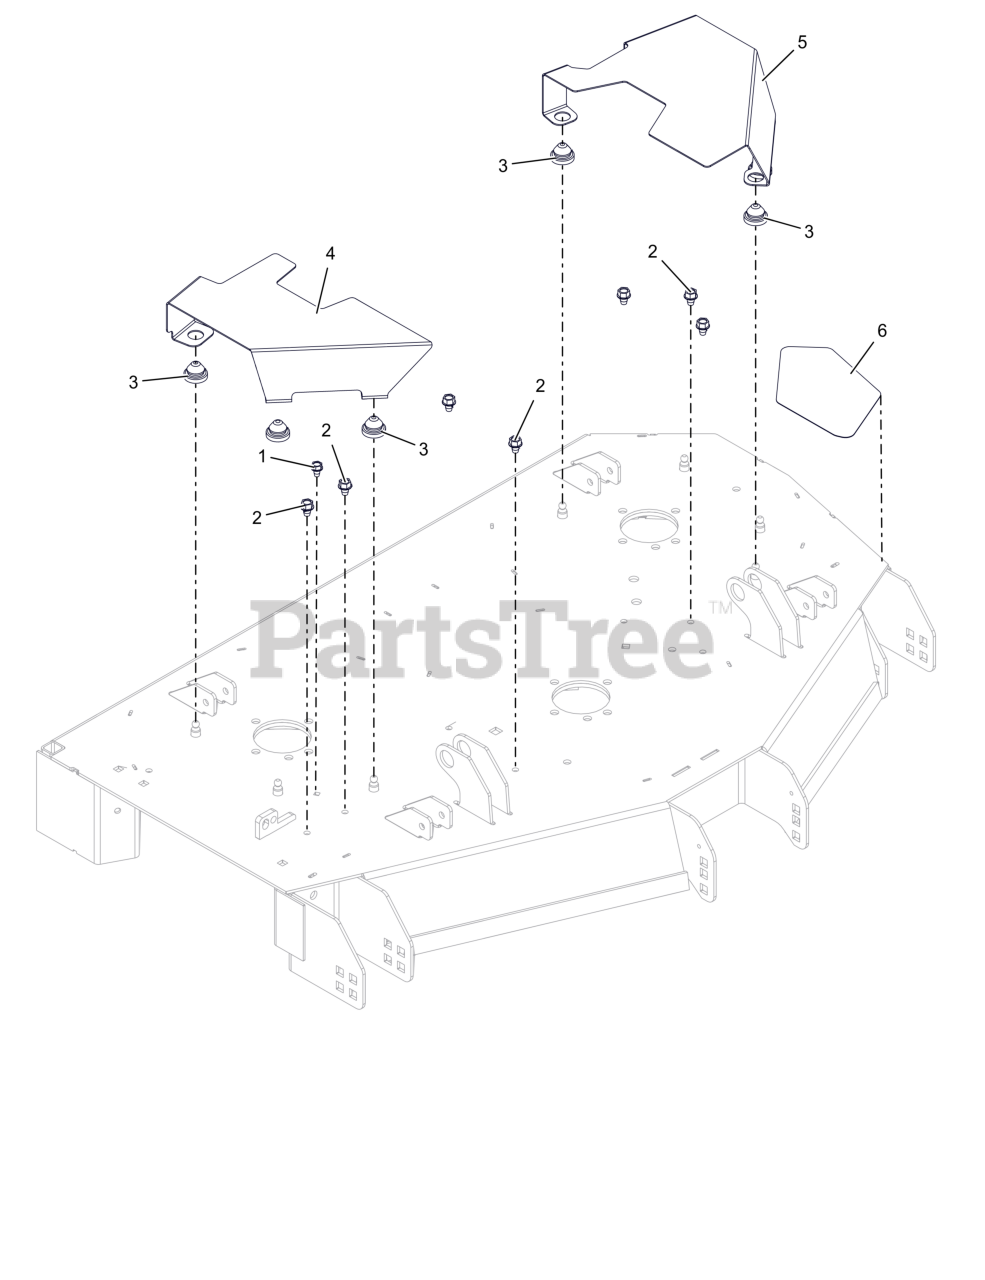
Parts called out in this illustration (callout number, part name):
1	SCR,TAP .312-18X.50 HWH TR ZCC
2	SCR,TAP .375-16X.50 HWH TR ZCC
3	COUPLING, RUBBER PUSH-IN
4	COVER, BELT 44" RIGHT (RED)
5	COVER, BELT 44" LEFT (RED)
6	GRIP, STEP ANTI SKID HD 44 XF3
